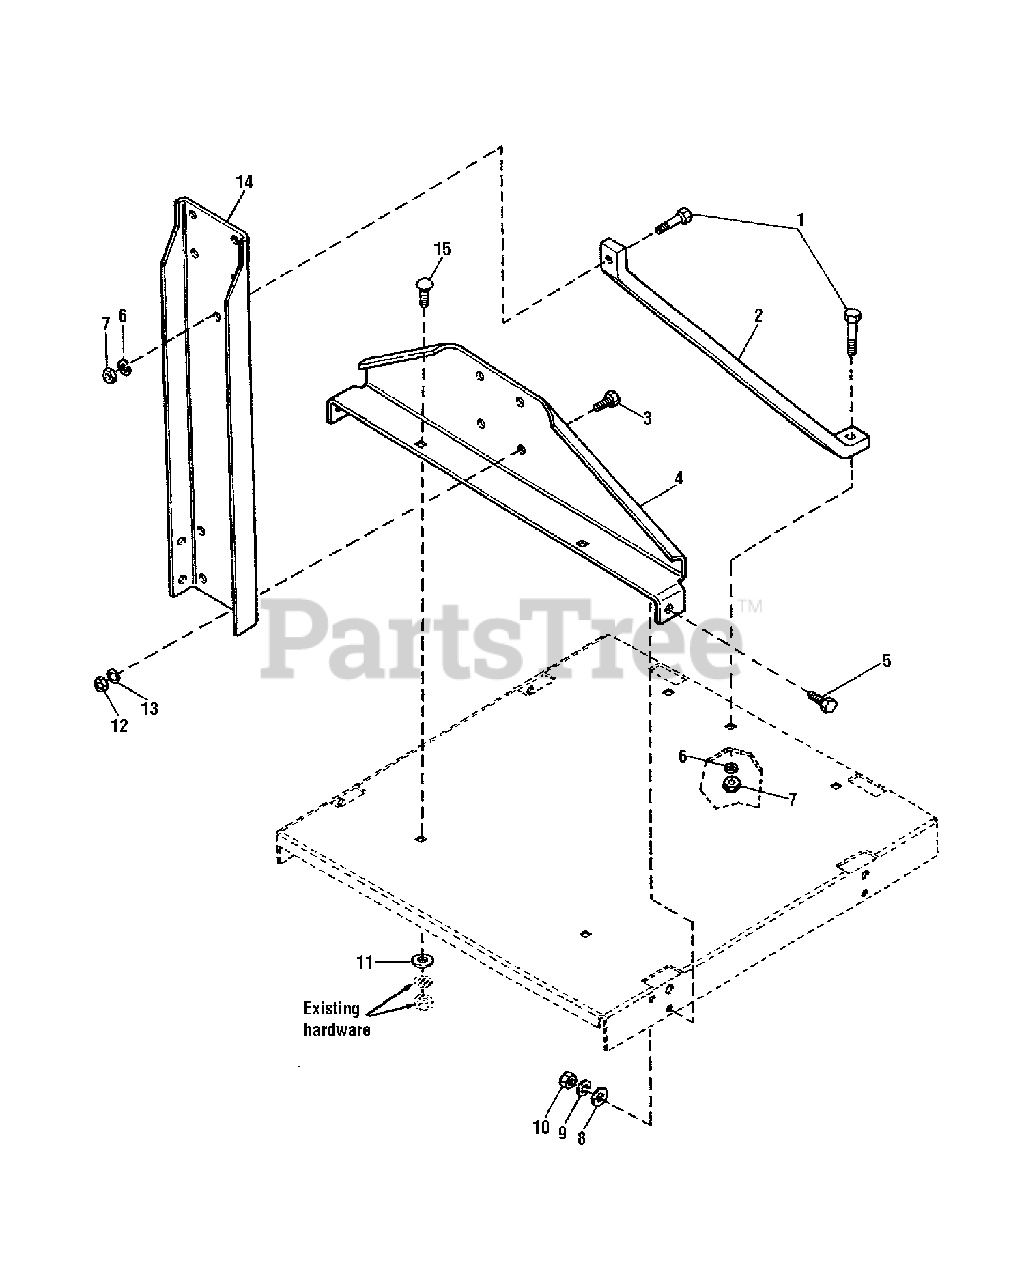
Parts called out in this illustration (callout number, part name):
1	CAPSCREW, Hex Head, 5/1 6-18 x 1-1/4
2	BRACE, Bar
3	CAPSCREW, Hex Head, 3/8-16 x 1
4	BRACKET, Lower
5	CAPSCREW, Hex Head, 1/4-20 x 5/8
6	LOCKWASHER, 5/16
7	NUT, Hex, 5/16-18
8	WASHER, 1/4
9	LOCKWASHER, 1/4
10	NUT, Hex, 1/4-20
11	WASHER, 5/16
12	NUT, Hex, 3/8-16
13	LOCKWASHER, 3/8
15	CARRIAGE BOLT, 5/16-18 x 1
